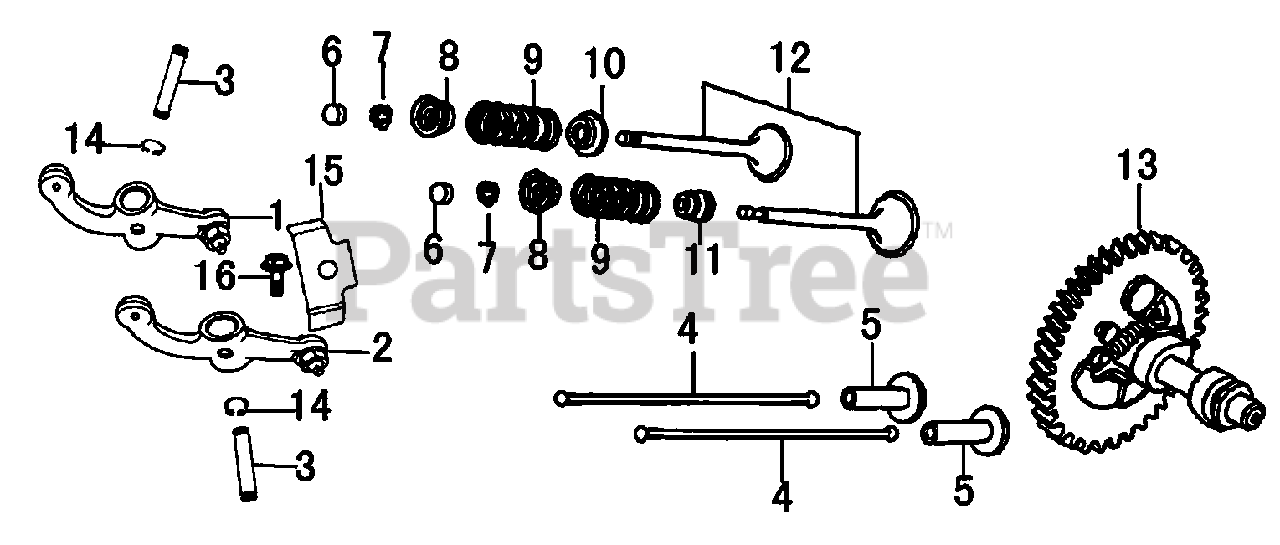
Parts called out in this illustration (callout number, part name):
1	ROCKER ARM ASSY.
2	ROCKER ARM ASSY.
3	VALVE ROCKER SHAFT
5	LIFTER, VALVE
6	ROTATOR, VALVE
7	LOCKER, VALVE
8	RETAINER, VALVE SPRING
9	SPRING, VALVE
10	SEAT, VALVE SPRING
11	SEAL, VALVE STEM
12	VALVE ASSY.
13	CAMSHAFT ASSY
15	RETAINER, ROCKER ARM SHAFT
16	BOLT, FLANGE
